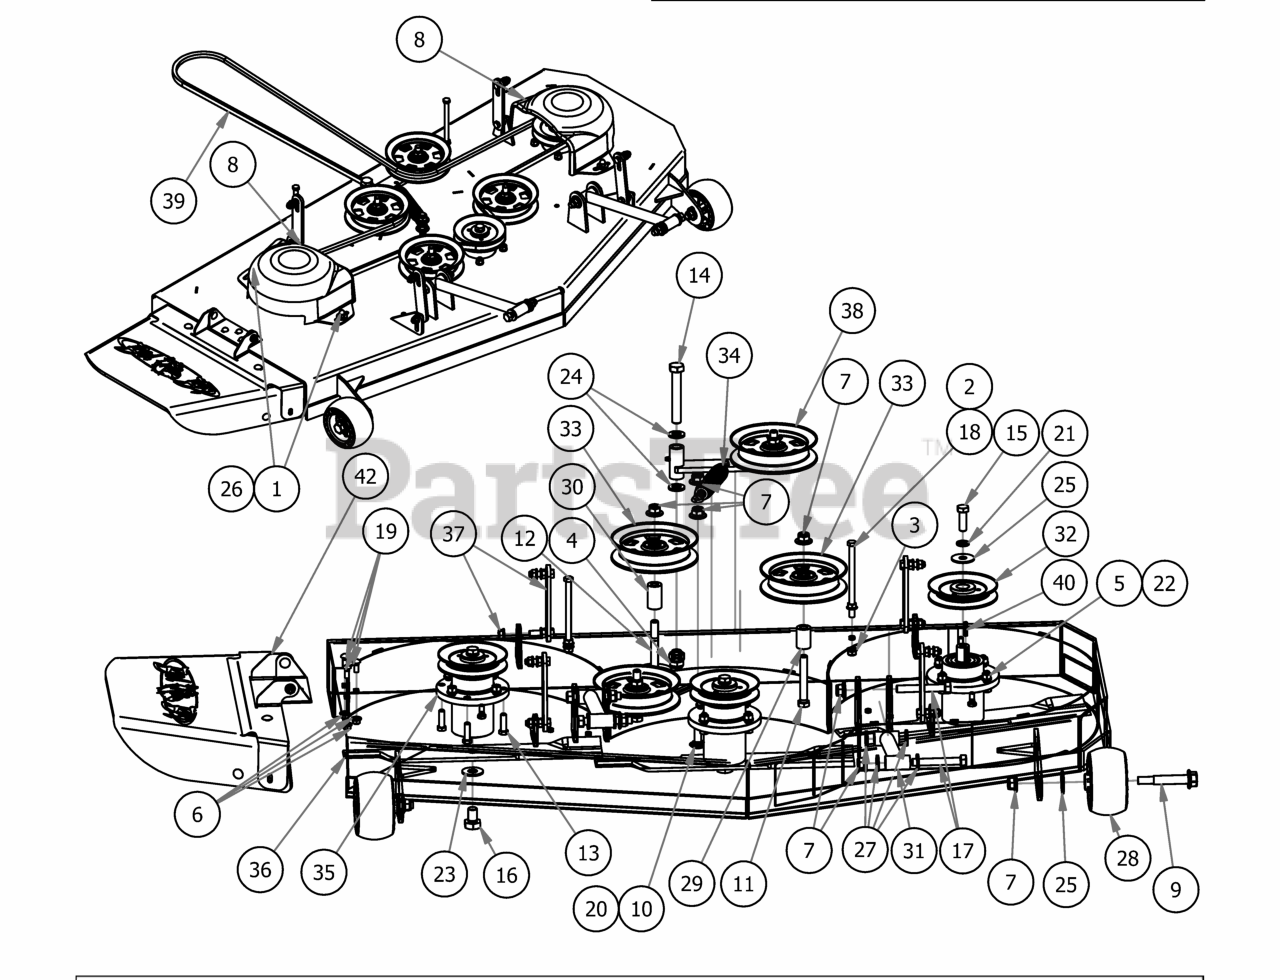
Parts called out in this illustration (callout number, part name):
1	Acorn nut-pulley Cover
2	3/8" Flange Nut
3	3/8" Nylock Flange Nut
4	5/8" Nylock (1/2 Jam)
5	3/8" Hex Nut
6	5/16" Nylon Flange Nut
7	1/2-13 Nylon Flange Nut
8	Pulley Cover
9	Deck Wheel Bolt
10	1/2 x 2" Carriage Bolt
11	1/2 x 3 1/2 Flange Bolt Grade 8
12	1/2" x 4" Bolt (Grade 8)
13	3/8" x 1 1/4" Hex Bolt
14	5/8" x 4" Hex Bolt
15	1/2"-20 x 1 1/2 - Grade 5 Fine Thread Bolt
16	5/8" x 1 1/2" Grade 8 Hex Bolt (Fine)
17	1/2-13 x 3 1/2 GR 5 Hex Bolt
18	3/8-16 x 5 1/2 Hex Bolt
19	5/16-18x3/4 carriage bolt
20	.517 Square Hole Round Washer
21	1/2" Lock Washer
22	3/8" Lock Washer
23	5/8'' Flat Washer
24	.630 ID Plastic Washer
25	1/2" Belleville Washer
26	.360 ID Plastic Washer-Black
27	.505 Nylon Spacer
28	Deck Wheel
29	.502 ID X .750 OD X 1.500 Long Spacer
30	1 3/4" Pulley Spacer
31	MZ/ZT Deck Locator
32	54 MZ Spindle Pulley
33	5-3/4 Idler Pulley
34	Deck Idler Spring
35	Spindle Assembly-MZ
36	54" MZ Fusion Blade
37	Deck Hanger Assembly
38	2017 54"/48" Deck Idler Assembly
39	B155.75 Deck Belt
40	3/16 x 1 Square Key
41	2017 54" MZ Magnum Deck
42	MZ Discharge Chute Assembly
